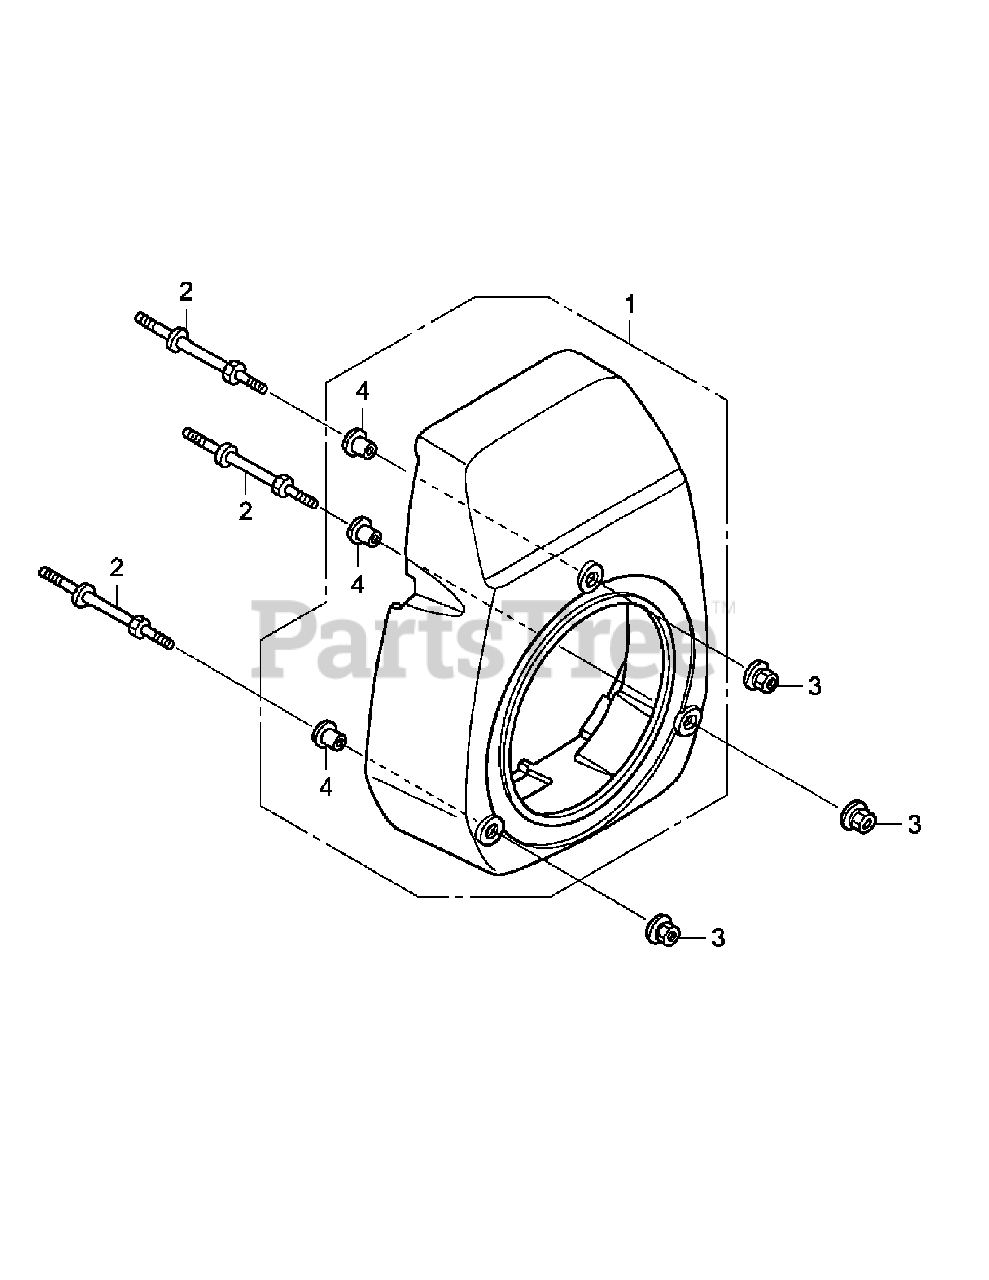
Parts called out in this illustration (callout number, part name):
1	Fan Cover (Black)
3	Flange Nut, 6mm
4	Fan Covar Collar
